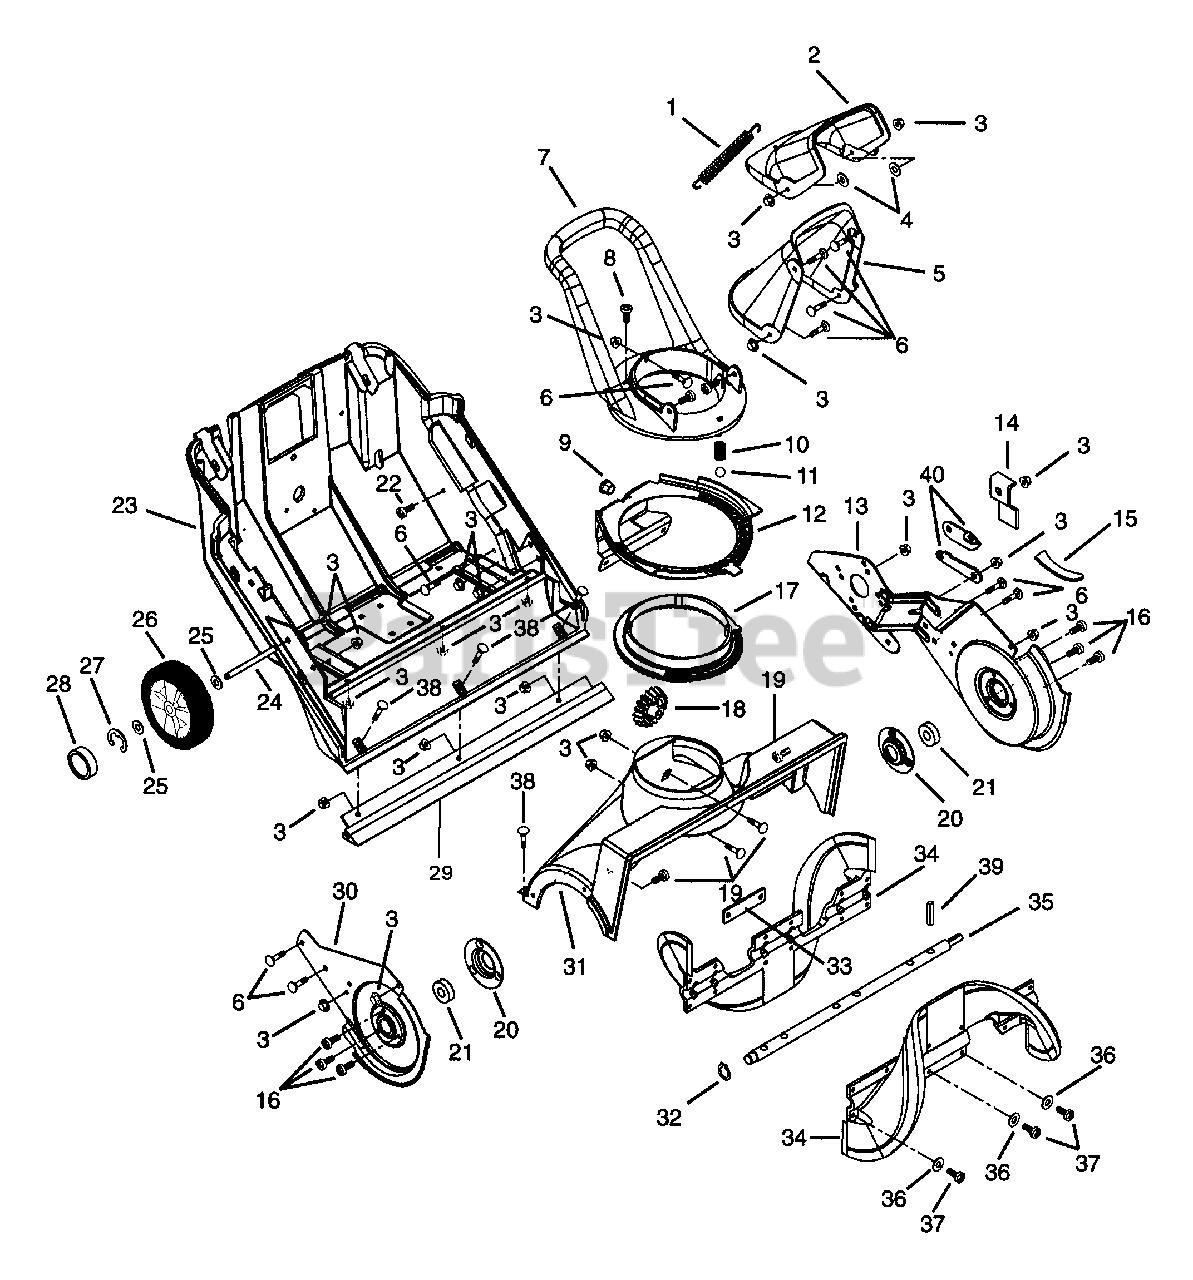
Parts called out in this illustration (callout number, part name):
1	SG-TENS
2	DEFLECTOR-DISCHARGE CHUTE ASSY
3	NUT-LK-FLG .250-20 PL BLK
4	WSHR-FL-RBR .31X1.25X.06
5	CHUTE-DISCHARGE
6	BLT-RDHDSQNK .25-20X.75 GR5PL
7	HANDLE W/HOLE SEE 03801800
7	HANDLE
8	SCR TAP 8-18X1.50 SL HWH PL B
9	BSHG-FLG .325X.444X.440X.560
10	SG-COMP .045X.360X1.75 WLD12.5
11	BALL .375 GRD 2000 CBN STL
12	BRKT-DISCHARGE CHUTE ROTATION
13	SUPPORT-BRG,REPLACEMENT ASSY
13	SUPPORT-BRG,LH
14	DEFLECTOR-EXHAUST
15	TAPE-ADHESIVE BACKED FOAM 11.0
16	SCR-TAP .250-20X.37 HWH PL TR
17	GEAR-DISCHARGE CHUTE SEGMENT
18	PINION-DISCHARGE CHUTE 18T
19	SCR-MCH .25-20X.50 TXTR PL
20	CUP-BRG
21	BRG-BALL .669X1.575X.47 (6203)
22	BLT-RDHDSQNK .25-20X1.00 GR5
23	CHASSIS
25	WSHR-FL-STL.406X.812X.065PL
26	T/WHL ASSY 7.0X1.5
27	RG-RTNG-EXT .375X.035
28	CAP-HUB
29	SCRAPER
30	SUPPORT-BRG,REPLACEMENT ASSY
30	SUPPORT-BRG,RH
31	HOUSING-IMPELLER ASSY
32	RG-RTNG-EXT .672X.035
33	PLATE-BOLT,SELF-TAPPING
34	IMPELLER HALF
35	KIT-IMPELLER REPLACEMENT
35	SHAFT-IMPELLER
36	WSHR-FL-STL .281X1.000X.063
37	@SCR-TAP .25-20X1.00 HWH TR YZ
38	SCR-MCH .25-20X.75 TXTR YWZC
39	PIN-ROLL .250X1.75 ZINC PL
40	ARM-SPRING
40	BRKT-SPRING
41	SCRAPER BLADE, UHMW-PE
